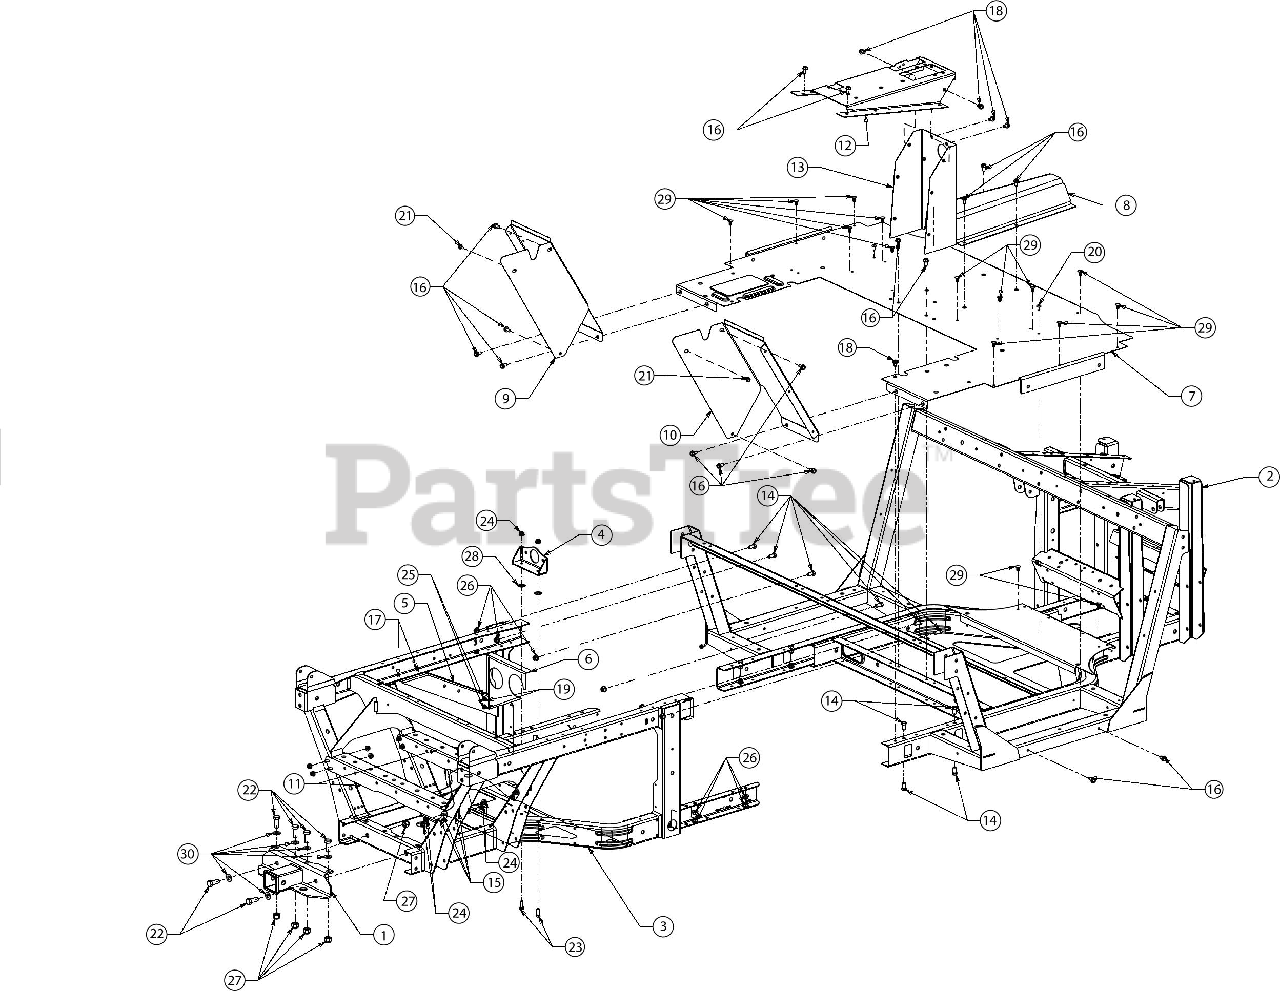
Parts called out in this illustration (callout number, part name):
1	UV HITCH ASSEMBLY
2	UV FRONT FRAME ASSEMBLY
3	FRAME ASSEMBLY-RR UV 4X
4	ISO TRAN MOUNT ASSEMBLY
5	AIR FILTER MOUNT BRACKET
6	HOSE SUPPORT BRACKET ASSEMBLY
8	FRONT DRIVE SHAFT COVER
9	SHIELD BRACKET (LH)
10	SHIELD BRACKET (RH)
11	REAR CHAIN SUPPORT
12	CONSOLE TOP PLATE
13	CONSOLE FRONT PLATE
14	HEX SCREW 3/8-16 x .75
15	SCREW 5/16-18
16	SCREW 5/16-18 x .750
17	SCREW 1/4-20 X.500
18	SCREW 5/16-18 x .500
19	SCREW 1/4-20 x .620 GR5
20	SCREW 1/4-14 x .625
21	SCREW 1/4-20X.625
22	SCREW 1/2-13 x 1.25 GR5
23	SCREW 5/16-18 x .875 GR5
24	FLANGE LOCK NUT 5/16-18
25	FLANGE LOCK NUT
27	HEX LOCK NUT NYLON
28	PUSH ON NUT
29	RETAINER PAN CLIP
30	FLAT WASHER .510 x 1.00 x .060
